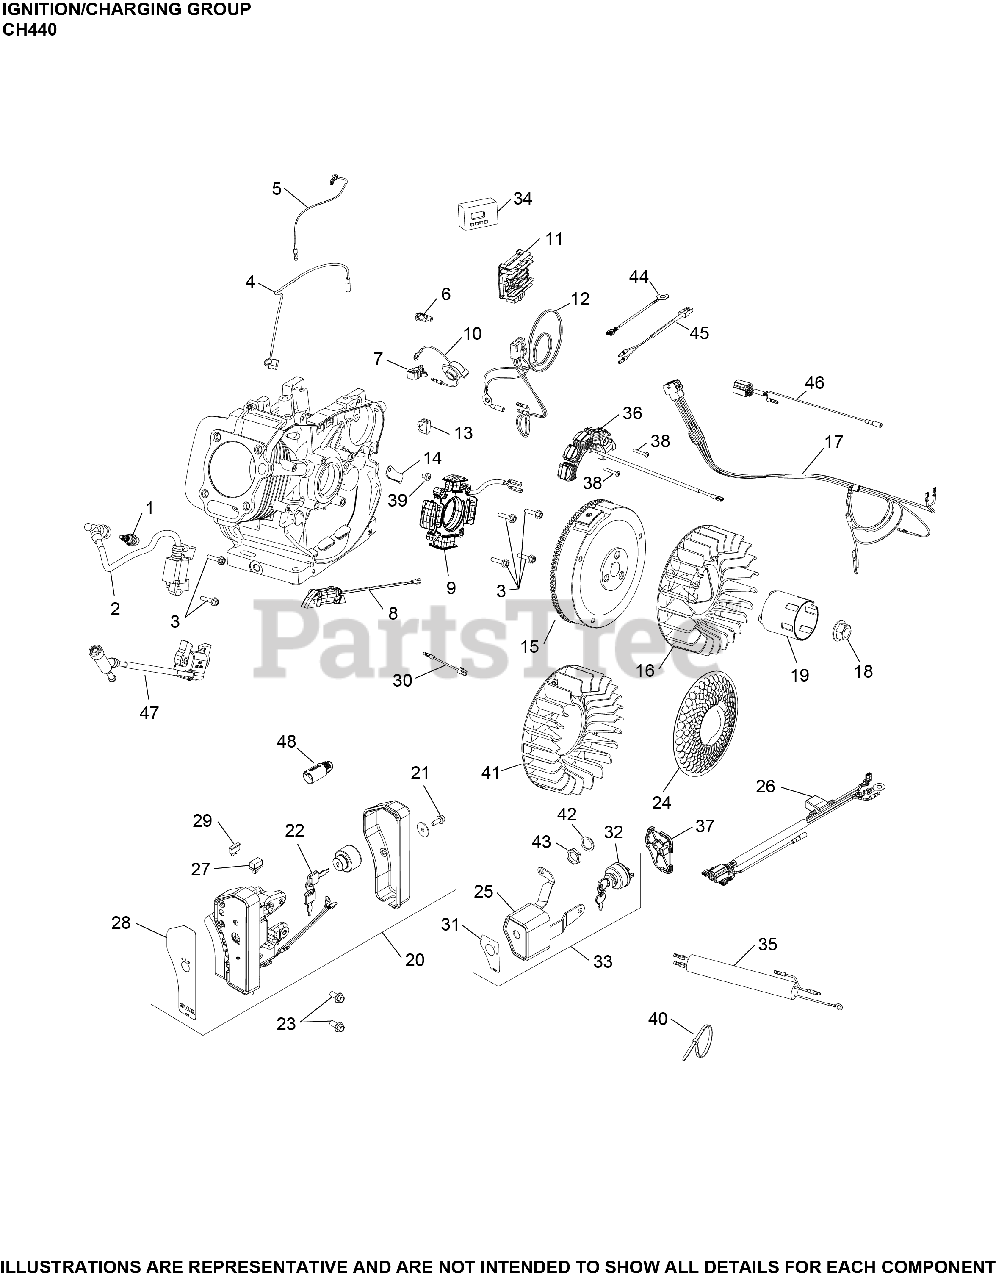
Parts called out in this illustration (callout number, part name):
1	SPARK PLUG
2	MODULE, IGNITION
3	SCREW, M6 X 25 USE 25 086 436-S
4	LEAD, GROUND TO KILL
9	STATOR ASSEMBLY, 18A
11	REGULATOR, 18 AMP
12	HARNESS, REGULATOR WIRING ASSY
14	BRACKET, STATOR WIRE
15	FLYWHEEL ASSY ELECTRIC START (CH440)
16	FAN, FLYWHEEL
18	NUT, FLYWHEEL
19	CUP, STARTER DRIVE
21	SCREW, HEX FLANGE (M6)-USE 25 086 433-S
25	KEYBOX HOUSING ASSEMBLY
26	HARNESS, WIRING ASSEMBLY (18 AMP)
31	LABEL, KEY BOX
32	SWITCH, KEY ASSEMBLY
33	KIT, KEY BOX ASSEMBLY
37	COVER, KEY BOX
38	SCREW, STATOR MOUNTING (CKY)
39	SCREW, COIL BRACKET (CKY)
